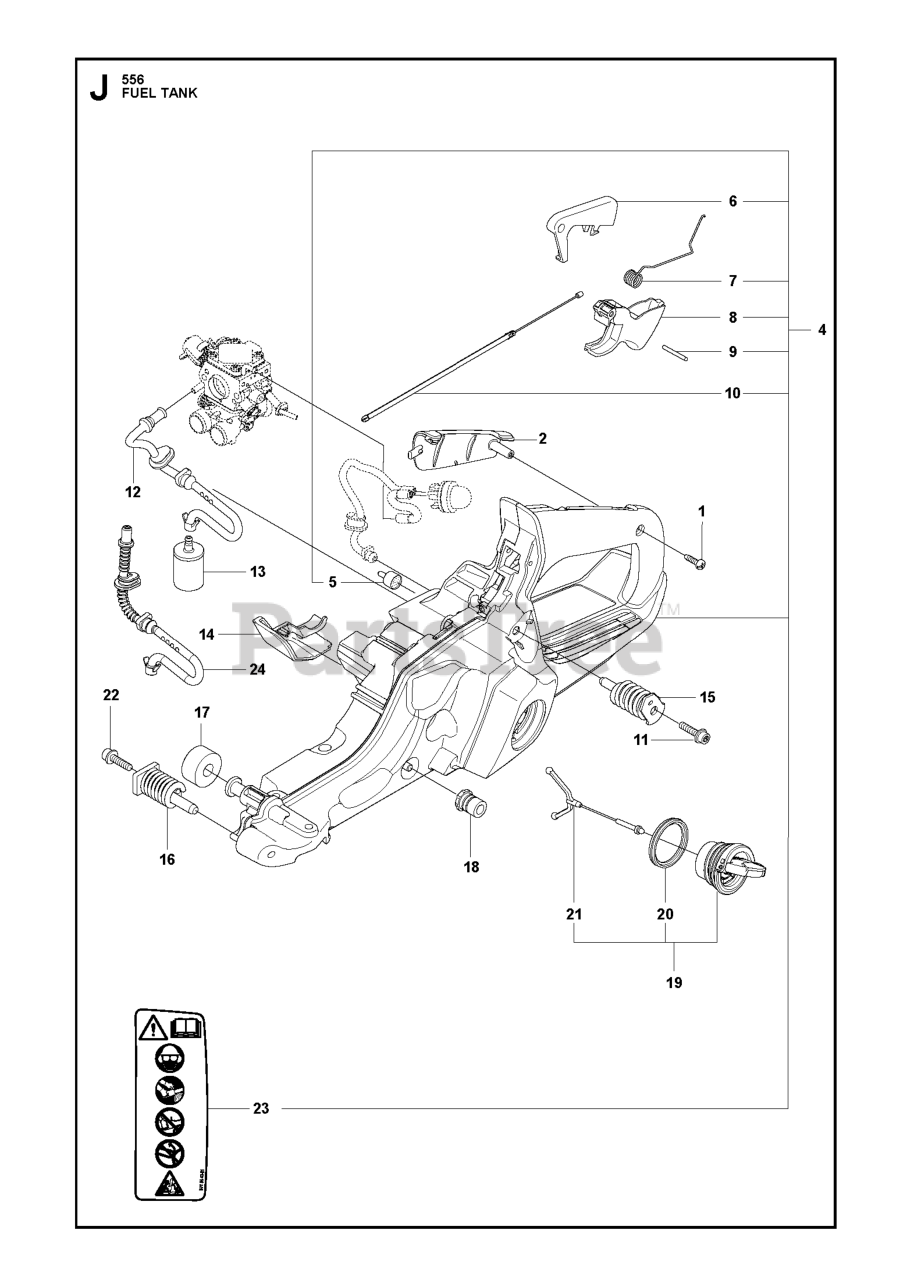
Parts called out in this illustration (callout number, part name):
2	SQUARE KEY
6	BUSHING.SNAP.NYL.BLK.
17	SPRING
26	SPRING.RETURN.CRUISE
29	ROD ROD BRAKE K46 TCRD GEN 2
30	WASHER
35	ROD .BRAKE. PARKING. GT. HUSQ.
37	WASHER.HARDENED
38	NYLINER SNAP 5/8" ID
42	PEDAL COVER T
50	IDLER.FLAT.910.OFFSET
51	NUT LOCK FLG 3/8-16 UNC
52	IDLER.V-GROOVE.910.OFFSET
56	BELT BELT DRIVE GROUND 114.25
61	PULLEY PULLEY INPUT FLANGED TR
64	SHAFT.ASM.PEDAL.BRK.CNTR
73	BOLT HEX 5/16-18 GR 5
90	KEEPER KEEPER BELT CLUTCHING T
92	BOLT
99	ROD ROD BYPASS CRD TEX GEN 2
103	JAM NUT TI
116	NUT LOCK HEX FLANGE 5/16-18
125	SCREW
140	LOCKWASHER
143	Screw 5/16-18 x 1/2 Hex, Self Tapping 5/16-18 x 1/2
159	COTTER PIN
160	RETAINER CLIP
161	SPRING, RETURN LT
163	ROD ROD CONTROL SHIFT PEDAL TC
166	NUT.PUSH.625
167	LATCH.BRAKE.SPRING
175	SHAFT SUBASM.SHAFT.CROSS.SHIFT
183	SPACER AXLE
184	RB HANDLE.PARKG.BRK.HUS/PRED
186	SPACER.RETAINER
188	RP.LINK.CLUTCH.GROUND.DRIVE
189	BELLCRANK BELLCRANK GROUNDDRI
195	BRACKET.ROD.BRAKE
196	SCREW 3/8-16X1
197	CLUTCH.ANTIROTATION.WIREFORM.
203	WASHER
206	BRACKET.MOUNT.CRUISE.LATCH
207	LATCH.CONTROL.CRUISE
208	GEAR.SECTOR.CONTROL.CR
209	ROD.CONTROL.CRUISE.GT.
210	ROCKER.ASM.PEDAL.CONTR
211	BEARING.NYLON
213	KNOB.CONTROL.CRUSIE.HU
214	PEDAL.FORWARD.PAD.TEX
215	PEDAL RUBBER REVERSE
221	RETAINER.SPRING.CLIP.H
222	WASHER 21/32 X 1-1/4 X 10 GA.
226	BRACKET.MOUNT.TORQUE.K46.TLT
227	SCREW.THDROL.5/16-18X3/4.TTY
279	LINK SUBASM. LINK AND STUD
309	PLATE FASTENING LT
311	WASHER NYL
312	HUB.TAPERED.ROUND.CRD
314	RETAINER KEEPER BELT
315	BOLT.5/16-18X1.25
335	PULLEY.V-IDLER.
339	STRAP STRAP TORQUE K46 CRD TE
342	BELT GUIDE
351	BRACKET BRACKET DECK SWAY
352	BRACKET BRACKET IDLER CRD TEX
355	STRAP STRAP TORQUE K46 CRD TEX
359	SCREW LT.3/8-46X5/8
360	NUT NUT HEX CENTERLOCK 5/16-24
362	IDLER.FLAT.2.25.INCH
363	SPACER SPACER 343X63X.62
364	BRACKET BRACKET IDLER CRD TEX
